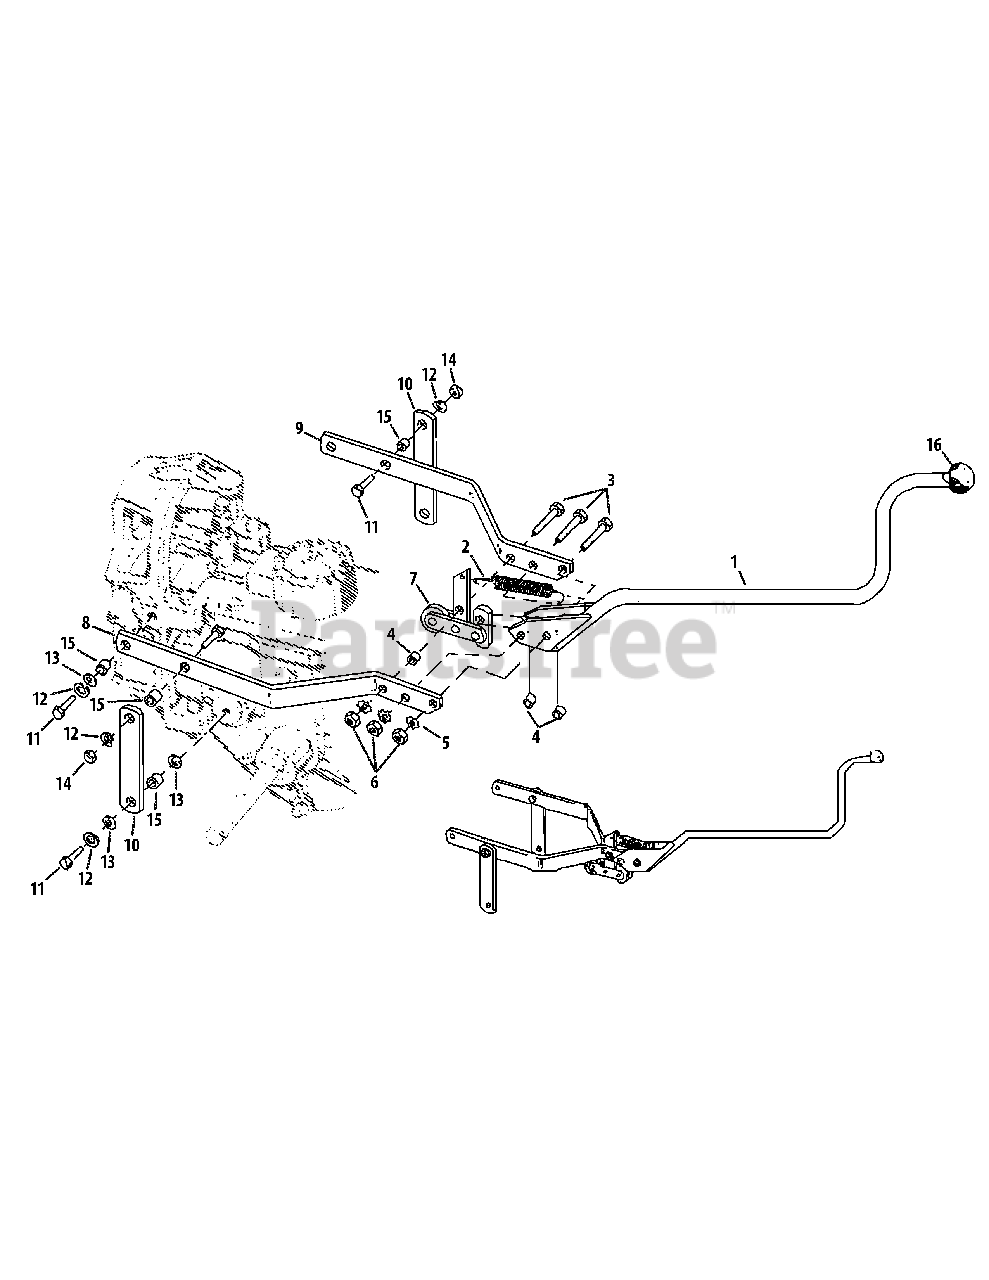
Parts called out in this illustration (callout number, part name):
1	Forward/Reverse Lever
2	Clutch Pawl Spring
3	Hex Bolt, 5.16-18 x 1 1/2
4	Bushing, .5 x .316 x .375
5	External Tooth Lockwasher, 5/16
6	Hex Nut, 5/16-18
8	Yoke (Left)
9	Yoke (Right)
10	Yoke Pivot Link
11	Hex Bolt,3/8-16 x 1
12	Lockwasher, 3/8
13	Flat Washer, 3/8
14	Hex Nut, 3/8-16
15	Bushing Spacer, .5 x .375 x .3
